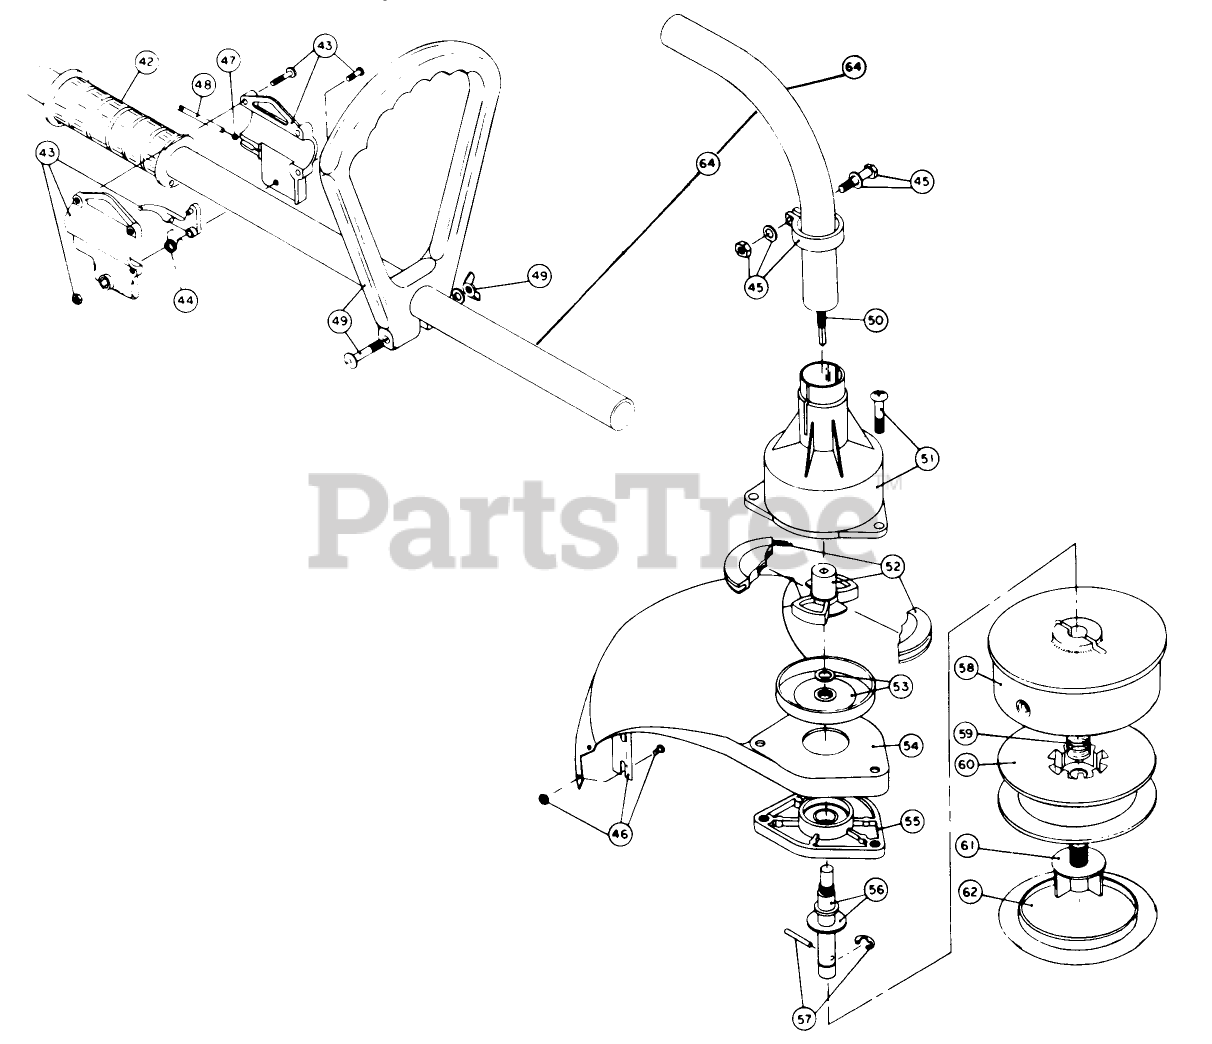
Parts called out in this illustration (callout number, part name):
44	THROTTLE TRIGGER SPRING
46	BLADE ASM
47	THROTTLE CABLE WIRE
48	THROTTLE CABLE HSG
51	CLUTCH HSG ASM
